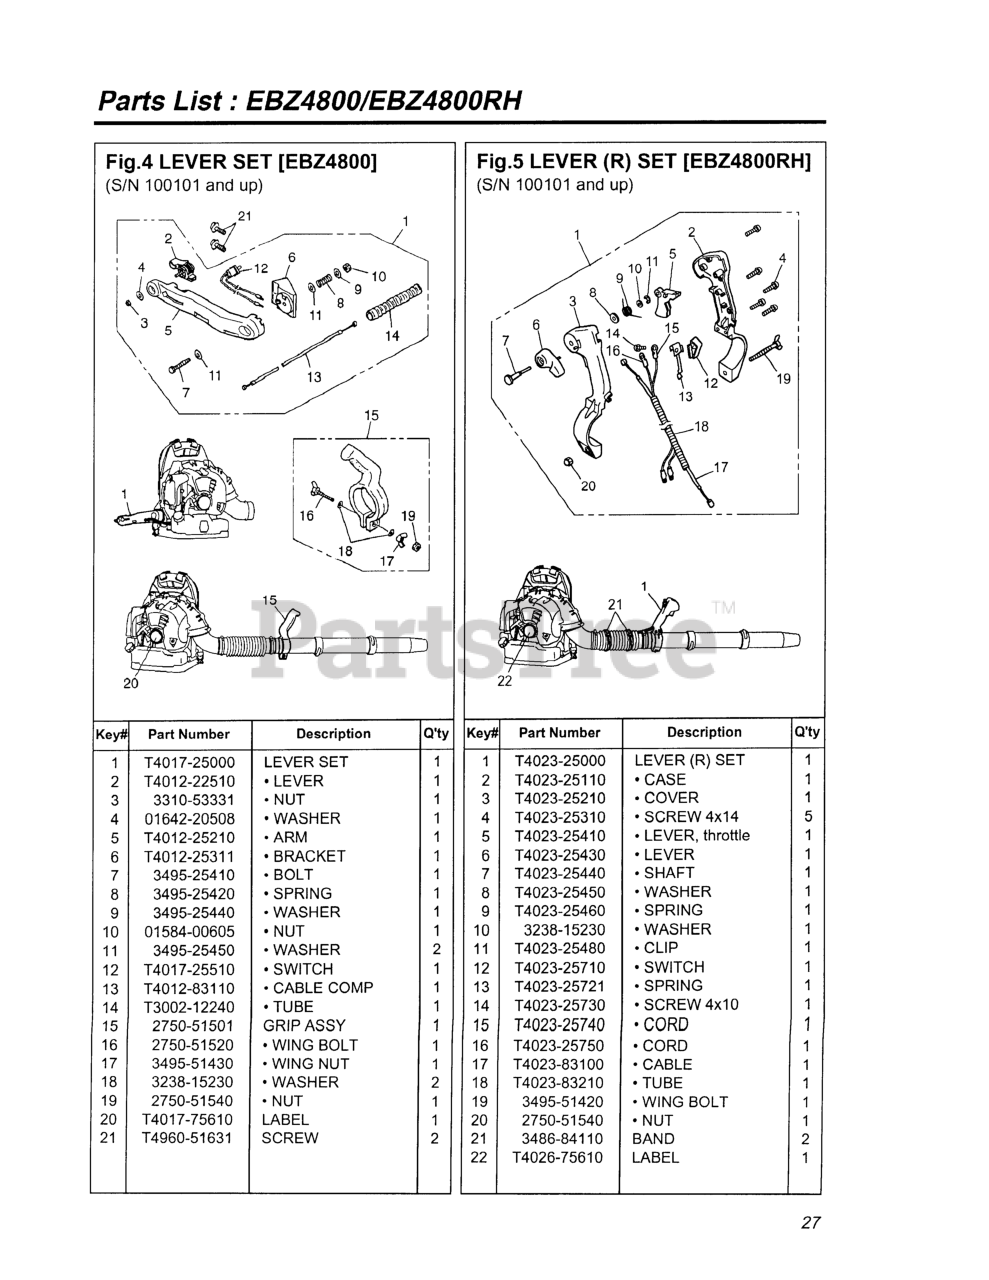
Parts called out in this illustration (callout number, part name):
4	SCREW 4X14
5	LEVER, THROTTLE
7	SHAFT
8	WASHER
9	SPRING WASHER
10	WASHER
11	CLIP
12	SWITCH
13	SPRING
14	SCREW 4X10
15	CORD
16	CORD
17	CABLE
19	BOLT, WING
20	NUT
21	BAND
22	LABEL, RECOIL (EBZ4800RH)
